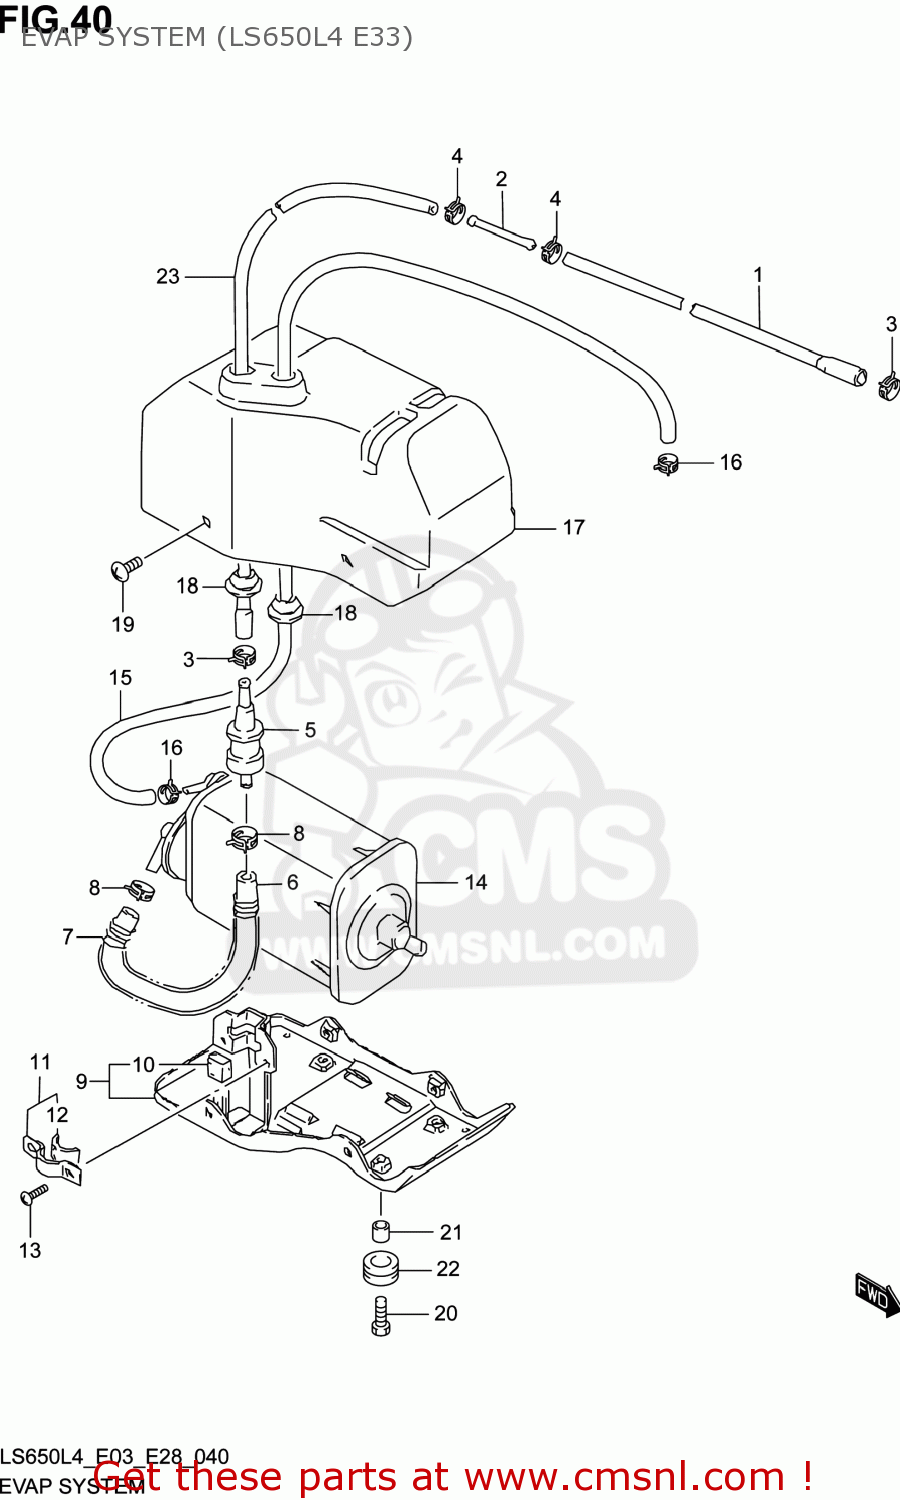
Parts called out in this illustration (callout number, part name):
1	HOSE,EVAP SYSTEM NO.3 CHG
2	JOINT
3	CLIP
4	CLIP
5	VALVE,FUEL TANK BREATHER
6	HOSE,EVAP SYSTEM NO.1
7	SPRING
8	CLIP
9	PLATE,CSTR FITING
10	CUSHION
11	PLATE,FUEL TANK BREATHER NO.2
12	CUSHION
13	SCREW
14	CANISTER ASSY,CHARCOAL
15	HOSE,EVAP SYSTEM NO.4 PURGE
16	CLIP
17	COVER,CANISTER
18	GROMMET
19	SCREW
20	BOLT(6X16)
21	SPACER(6.5X9X7.2)
22	CUSHION
23	HOSE,EVAP SYSTEM NO.2 CHG
